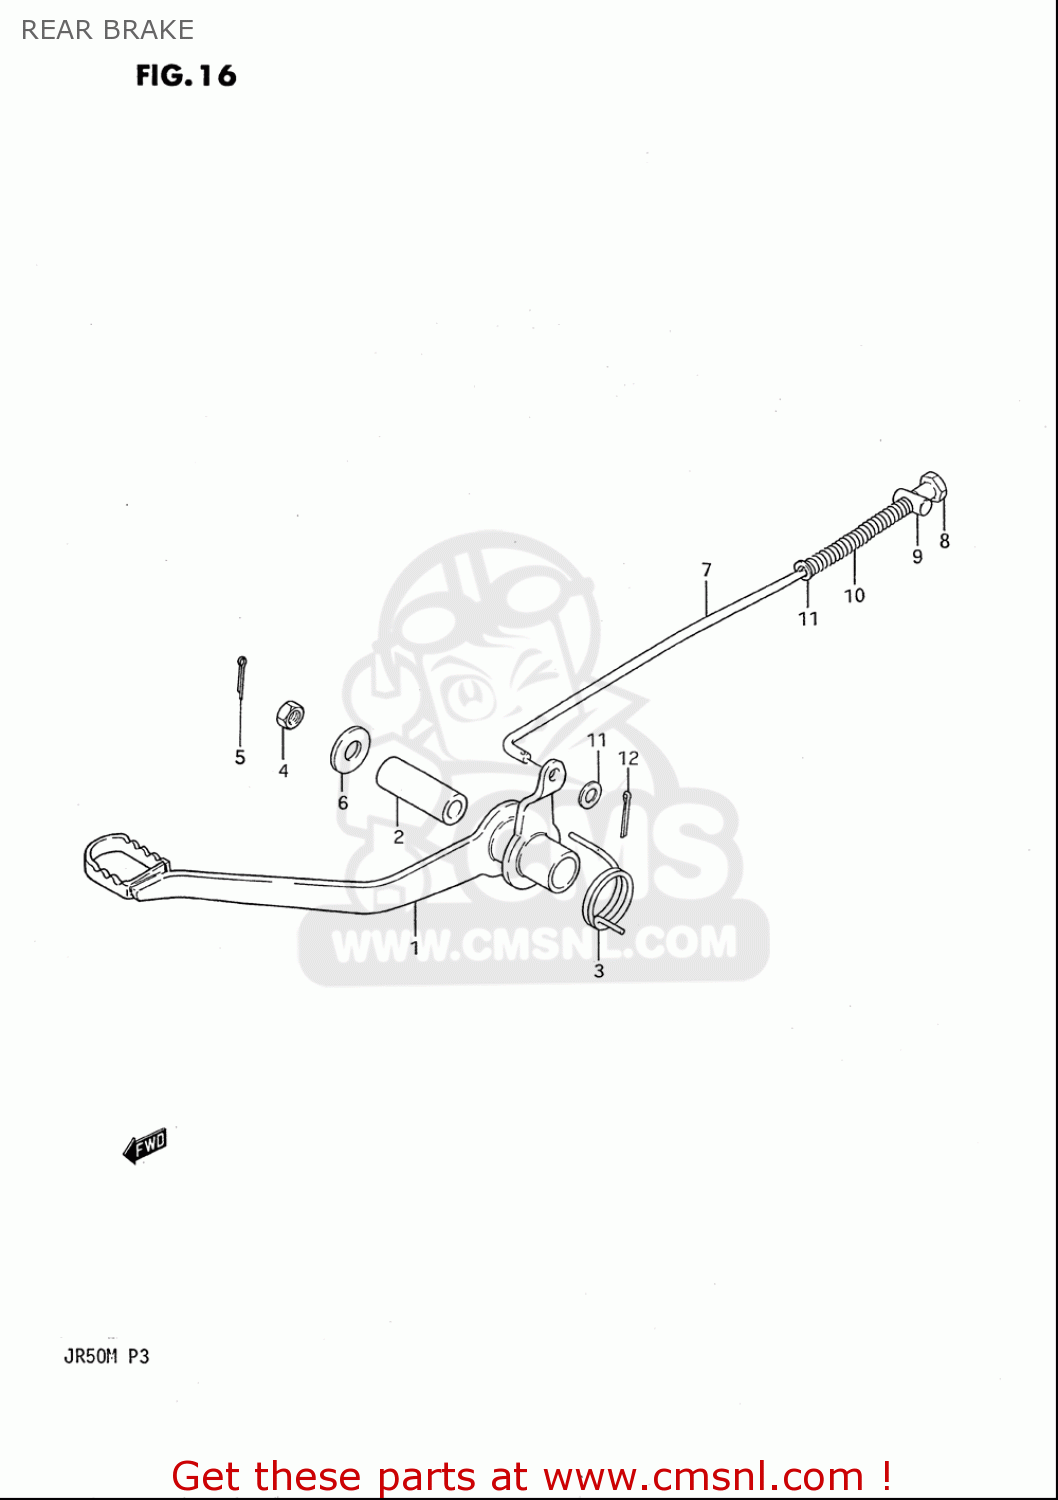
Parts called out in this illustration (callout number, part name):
1	PEDAL,BRAKE
2	SPACER,BRAKE PEDAL
3	SPRING,BRAKE PEDAL RETURN
4	NUT
5	PIN
6	WASHER
7	ROD ASSY,RR BRAKE
8	NUT
10	SPRING
11	WASHER
12	PIN
